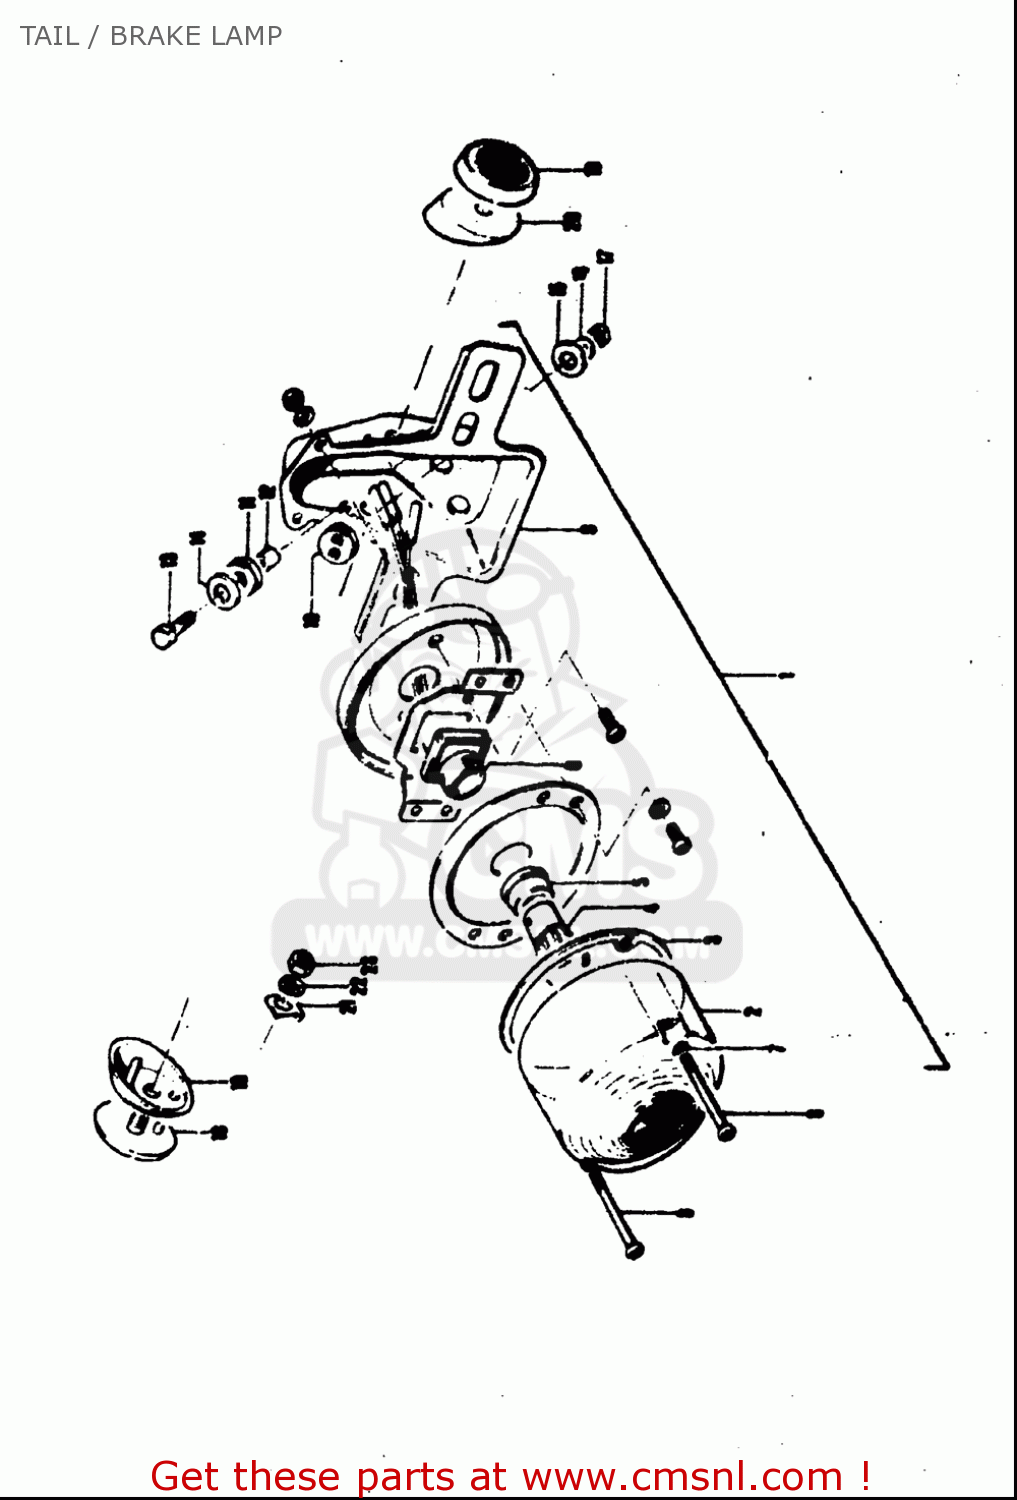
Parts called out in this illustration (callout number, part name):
2	LENS,RR COMBINATION LAMP
4	BULB(6V17/5.3W,STANLEY,A4813)
10	GROMMET,REAR COMBINATION LAMP
11	CUSHION
12	SPACER
13	BOLT
14	WASHER(6.5X20X1.6)
15	WASHER
16	WASHER,LOCK
17	NUT
22	WASHER,LOCK
23	NUT
